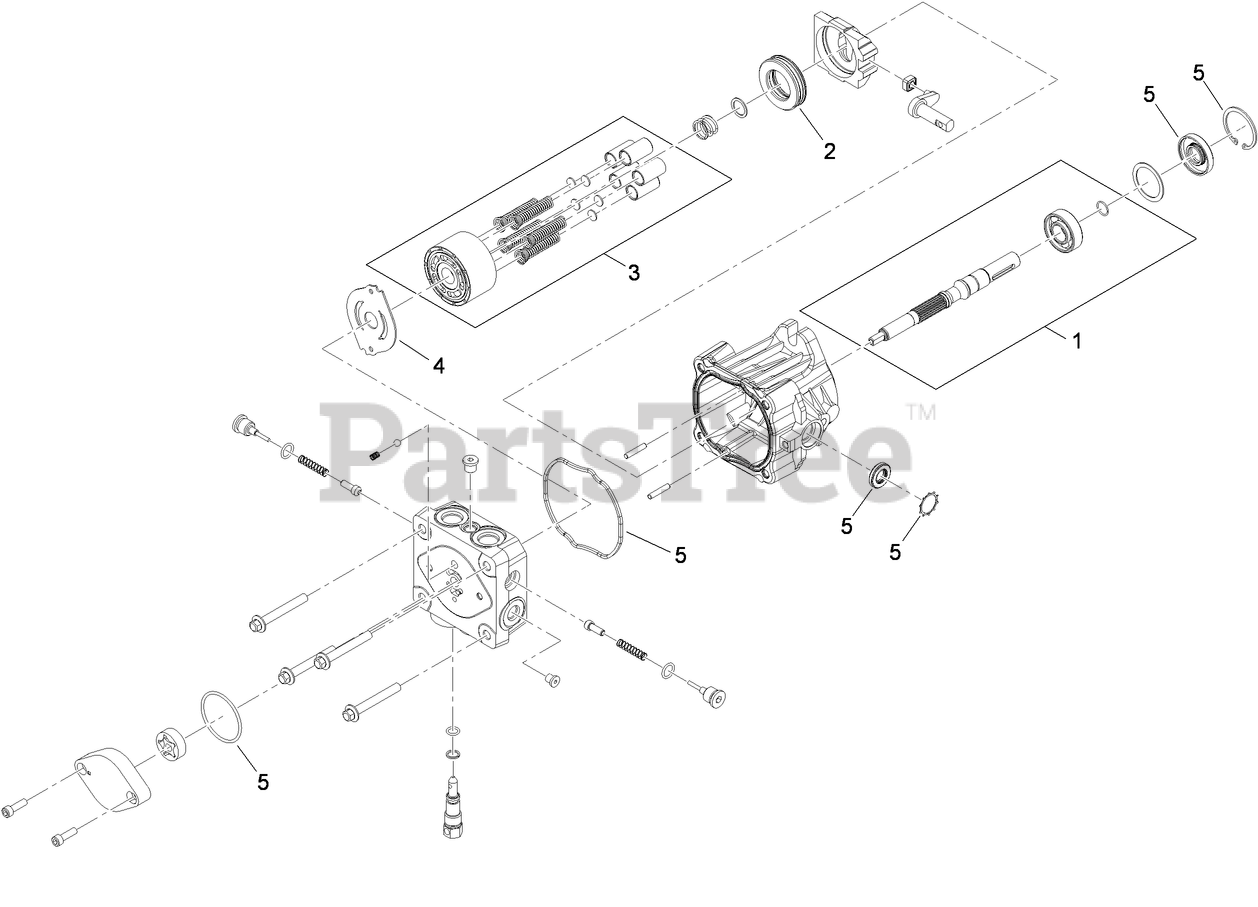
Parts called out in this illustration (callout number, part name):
1	INPUT SHAFT KIT
2	BEARING-THRUST
3	CYLINDER BLOCK KIT
4	Plate-Valve
5	SEAL OVERHAUL KIT
